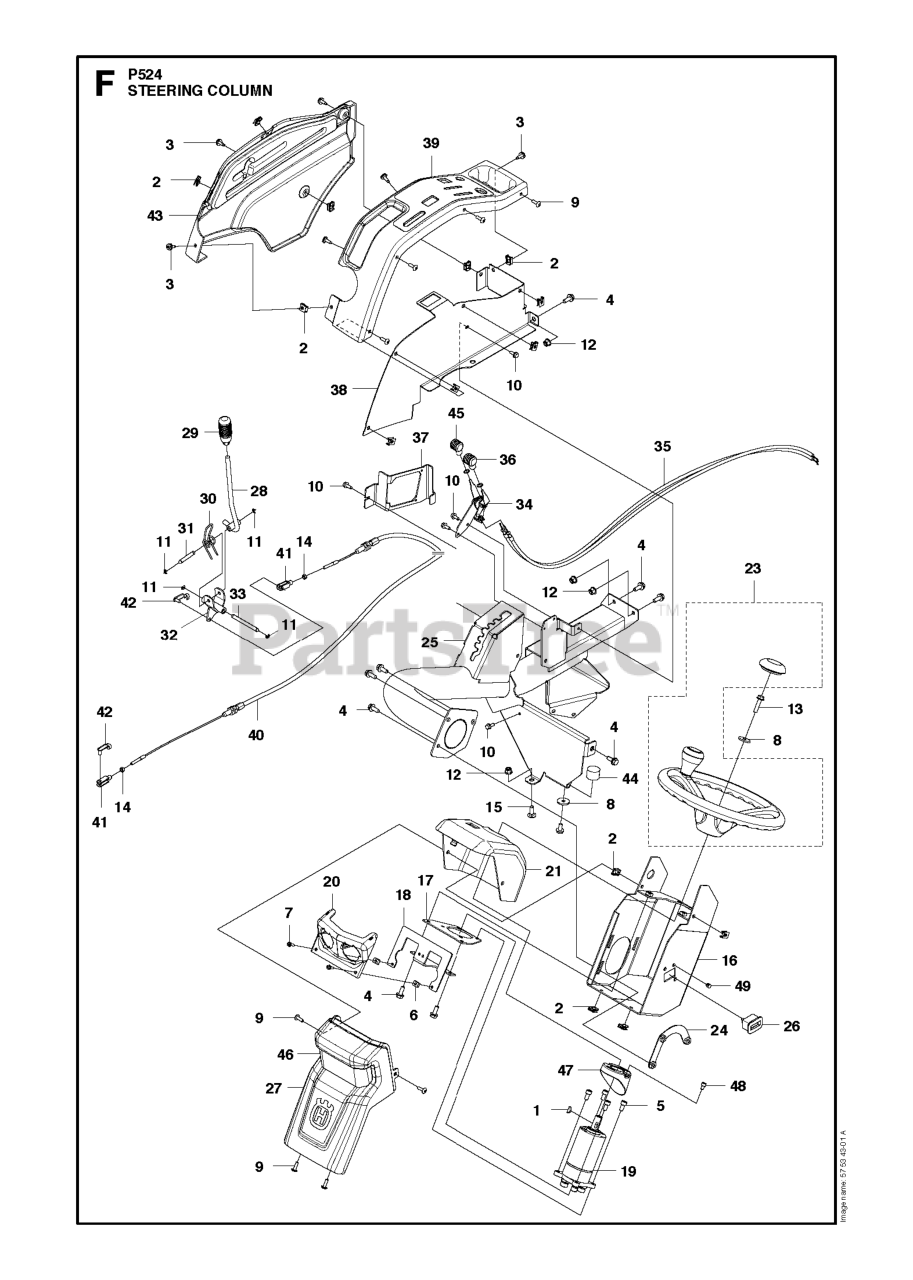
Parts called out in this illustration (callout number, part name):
12	NUT FLANGE
13	SCREW EHHFM
29	GEAR STICK KNOB
30	HAIR PIN SPRING
44	ANTIVIBRATION ELEMENT
48	SCREW MC6S 6X10
49	INSERT PIPE END
